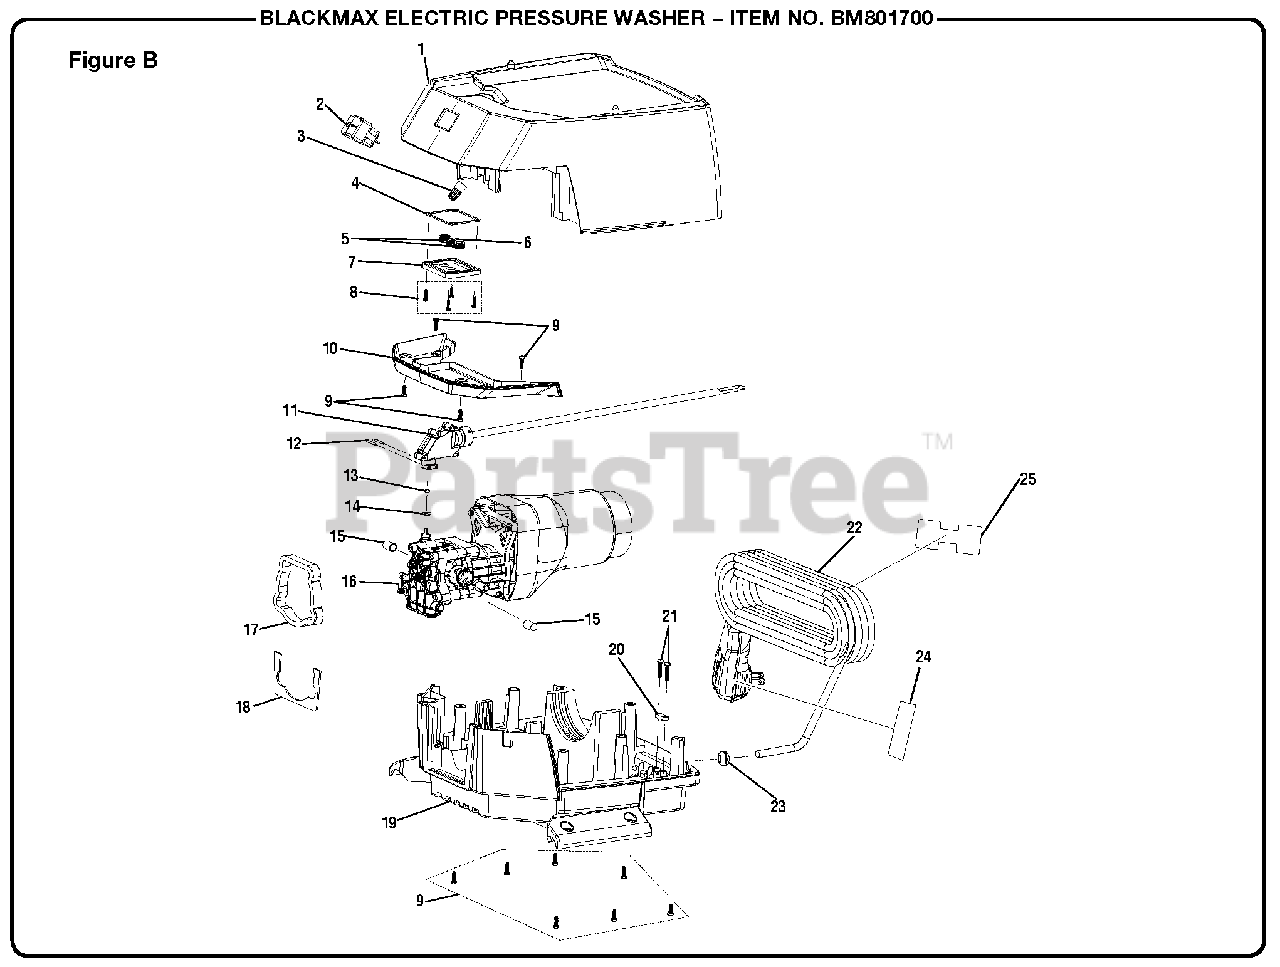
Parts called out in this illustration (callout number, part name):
1	Top Motor Housing
4	Switch Cover Gasket
7	Switch Cover
8	Screw (M3 x 14 mm)
9	Screw (M4 x 15 mm)
10	Pump Cover
11	Pressure Switch
13	O-ring
14	Brass Washer
16	Motor/Pump Assembly
18	Lower Gasket
19	Lower Motor Housing
20	Cord Clamp
21	Screw (M35 x 20 mm)
22	Power Cord
24	Cord Plug Label
25	Cord Wrap Warning Label
